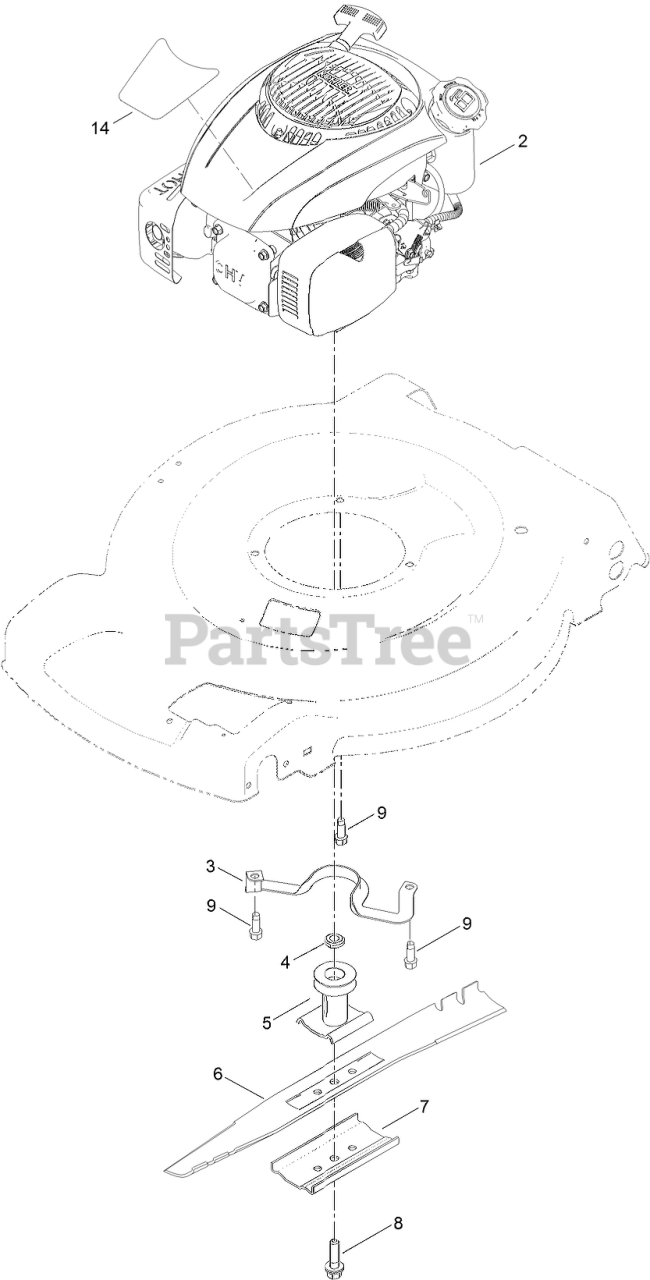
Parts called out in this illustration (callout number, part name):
3	Guide-Belt
4	Spacer-Driver
5	DRIVER-BLADE
6	BLADE-22 INCH
7	SUPPORT-BLADE
8	BOLT-BLADE
9	SCREW-TAPTITE
14	DECAL-SHROUD
